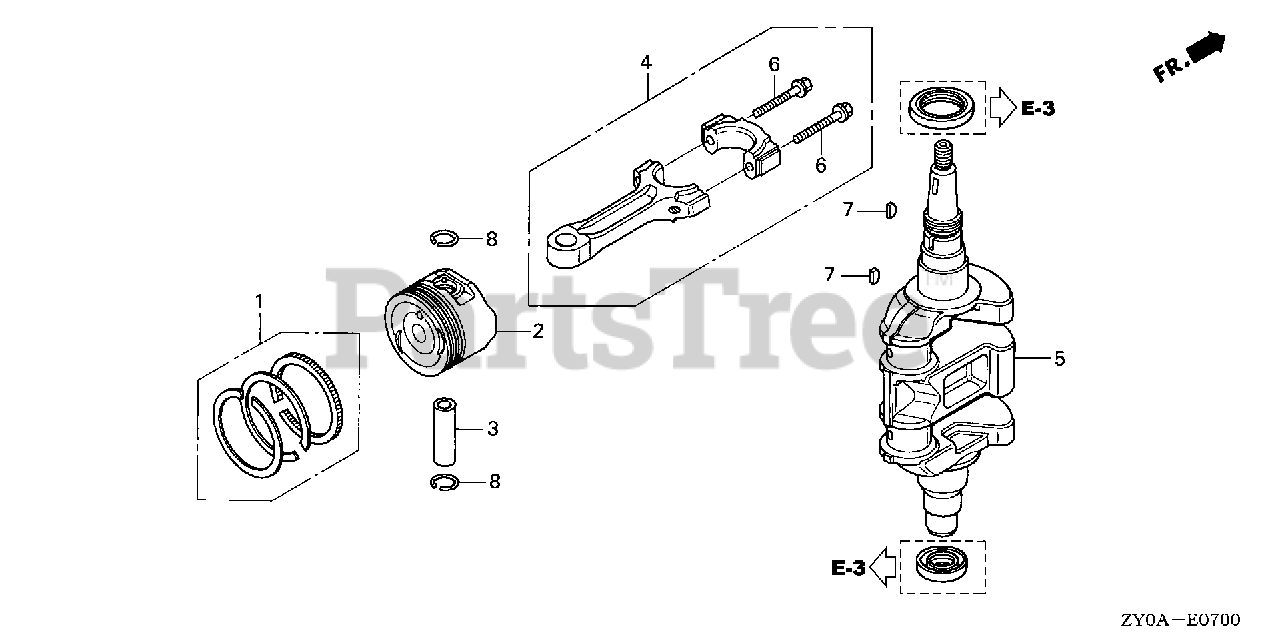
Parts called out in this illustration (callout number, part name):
1	RING SET, PISTON
3	PIN, PISTON
4	ROD, CONNECTING
5	CRANKSHAFT
6	BOLT, CONNECTING ROD (6X34)
7	KEY, SPECIAL (16X13)
8	CLIP, PISTON PIN (16MM)
